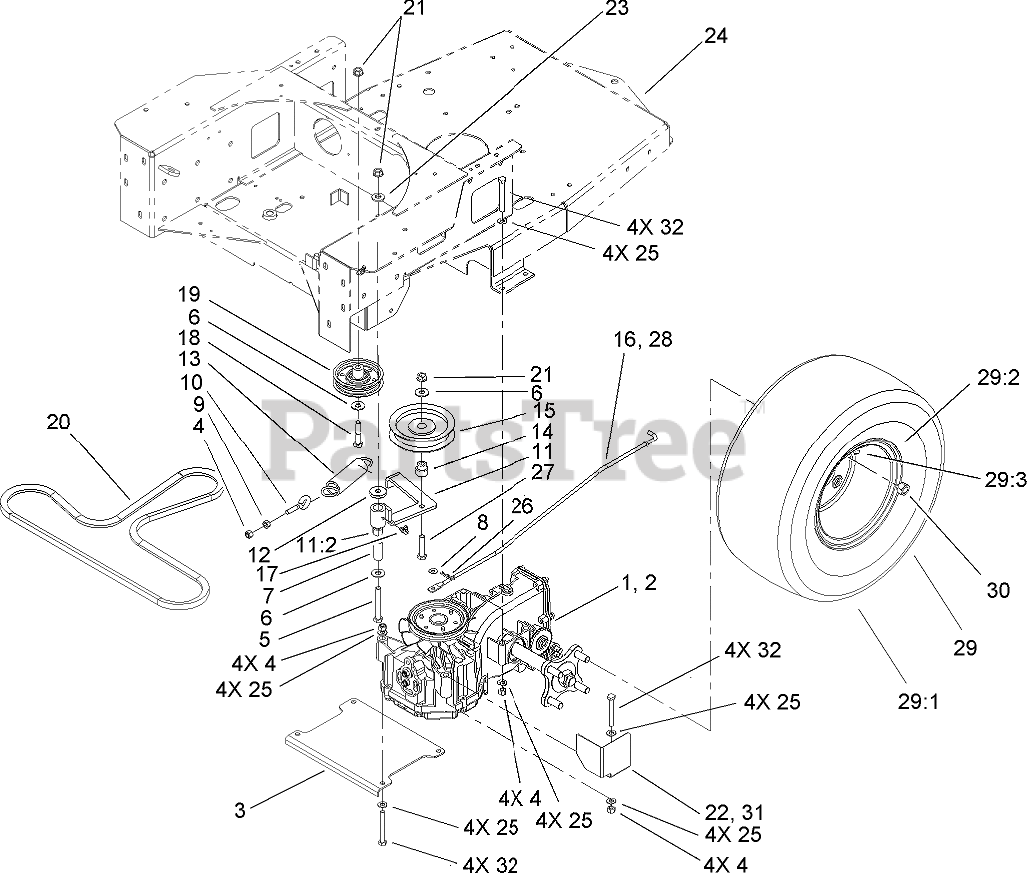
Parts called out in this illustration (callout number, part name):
1	Hydro-LH
2	Hydro-RH
3	PLATE-HYDRO, LOWER
4	NUT-LOCK, NI
5	SCREW-HH
6	WASHER-FLAT
7	BUSHING
8	WASHER-FLAT
9	NUT-HF
10	BOLT-EYE
11	IDLER ARM ASM
11:2	SLEEVE-BEARING
12	SPACER
13	SPRING-EXTENSION
14	BUSHING-IDLER
15	PULLEY-IDLER
16	ROD-RH
17	FITTING-GREASE, 90 DEG
18	SCREW-HH
19	PULLEY-IDLER
20	BELT-V
21	NUT-HF
22	GUARD-FAN, LH
23	WASHER-BELLEVILLE
25	WASHER-PLAIN
26	PIN-COTTER
27	SCREW-HH
28	ROD-LH
29	WHEEL AND TIRE ASM
29:3	STEM-VALVE
30	NUT-LUG
31	GUARD-FAN, RH
32	SCREW-HH
